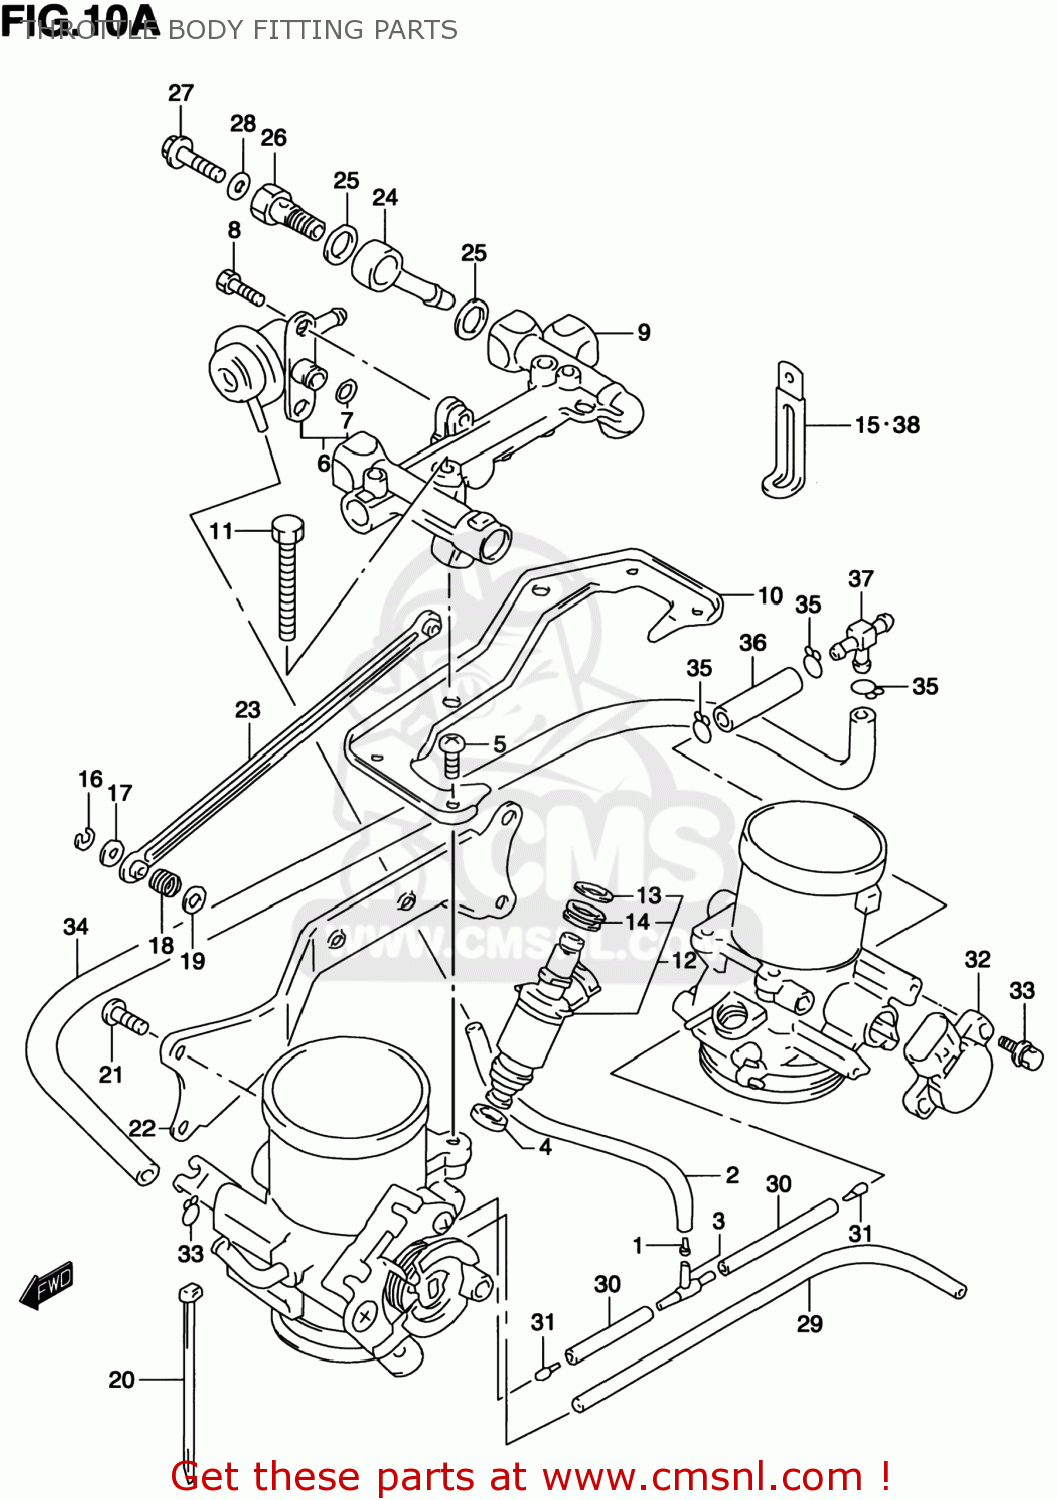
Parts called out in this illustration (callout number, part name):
1	JET
2	HOSE
3	3 WAY
4	CUSHION
5	SCREW
6	REGULATOR COMP,FUEL
7	O RING
8	BOLT
9	PIPE ASSY,DELIVERY
10	PLATE
11	BOLT
12	INJECTOR ASSY,FUEL
13	O RING
14	GROMMET
15	CLAMP(L:65)
16	E RING,ACCELETION LEVER
17	RING
18	SPRING
19	RING
20	CLIP
21	SCREW
22	PLATE
23	LEVER ASSEMBLY
24	UNION,FUEL HOSE
25	GASKET,UNION BOLT (NAS)
26	BOLT,UNION FUEL FILTER
27	UNION BOLT,AIR VENT
28	GASKET(5.8X13X1.2) (NAS)
29	HOSE
30	HOSE
31	JET
32	SENSOR ASSY,THROTTLE
33	SCREW
34	HOSE
35	CLIP
36	HOSE
37	NIPPLE
38	CLAMP(L:65)
